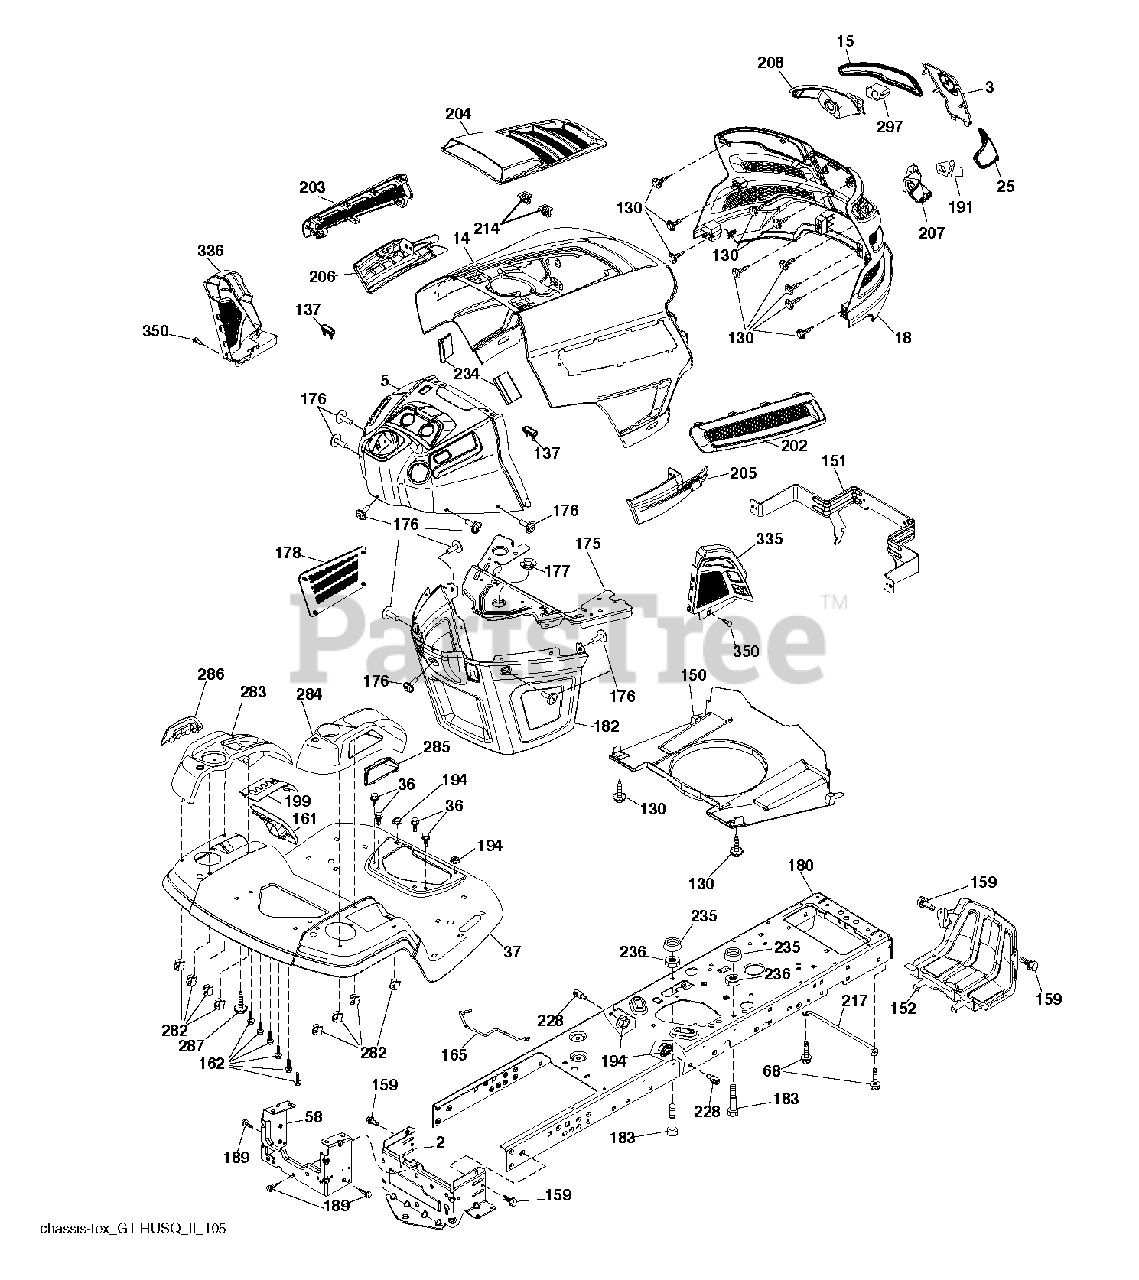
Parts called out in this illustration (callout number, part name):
2	DRAWBAR.LOWER.2PC.18/22
3	APPLIQUE.SUBASM.GT.HUSQ.II
5	DASH.UPP.GT2.DUAL.RD.PTO.MCHOK
14	HOOD.ASM.HUSQVARNA.GT.TEX.ORAN
15	LENS.HEADLIGHT.LH.GTII.2011
18	GRILLE.SUBSTRATE.2011.
25	LENS.HEADLIGHT.RH.GTII.2011
36	SCREW 5/16"
37	FENDER.TLT.FS.W/CPH/FW/RSF.668
58	DRAWBAR UPPER 2PC SMALL FENDER
68	SCREW LT
130	SCREW.#10 X 0.750.BOS
137	BUMPER DASH
150	AIR.DUCT.GTV.BLACK
151	BRACKET.PIVOT.HOOD.GT.HUSQ.II
152	SHIELD.BROWNING.PNT.GT.V2
159	SCREW, 3/8-16X3/4
161	WINDOW.FUEL.LT.HUSQ.TEX.498
162	SCREW.HI-LO.CONSOLE
165	SUPPORT.TANK.REAR.B/TE
175	PLATE.CROSSMEMBER.HUSQ
176	SCREW.#10-24X5/8.RN.QU
177	BUSHING, STEERING
178	CARGO.ASM.NET.TXGT.W/C
180	CHASSIS.TEX.BOLTED
182	DASH.LOWER.COMMON.12V.ADAPTOR
183	BOLT.5/16-18X1-1/4 FULL THD
189	SCREW
191	INSERT.REFLECTIVE.RH.HUSQ.GTII
194	NUT LOCK HEX FLANGE 5/16-18
199	PLATE.DECK.LIFT.HUSQ.LT
202	VENT.SIDE.RH.GT.HUSQ.II.
203	VENT.SIDE.LH.GT.HUSQ.II.498
204	VENT.TOP.HUSQ.GT2
205	SIDE.TRIM.RH.GT.HUSQ.II
206	SIDE.TRIM.LH.GT.HUSQ.II.GRAY
207	BEZEL LIGHT.RH.GT.II.MYLAR
208	BEZEL LIGHT.LH.GT.II.MYLAR
214	CLIP.RETAINER.TINNER.
217	ROD.PIVOT.HOOD
228	STUD.FASTNER.W/ANTI-ROTATE
234	BUMPER.HOOD.TEX.HUSQVARNA
235	SPACER FENDER
236	NUT.CENTERLOCK.5/16-
282	CLIP.RETAINER.CONSOLE.LT.HUSQ
283	CONSOLE.DECK.LIFT.R.SDFL.HUSQ
284	CONCOLE.CNTRL.PDL.HUSQ.LT.498
285	CONSOLE INSERT RH
286	CONSOLE.INSRT.LH.HUSQ.LT.BLACK
287	SCREW 1/4X20
297	INSERT.REFLECTIVE.LH.HUSQ.GTII
335	COVER.LOWER.DASH.RH.BLACK
336	COVER-LH.LOWER.DASH.GT2.BLACK
350	CLIP.X-MAS.TREE
